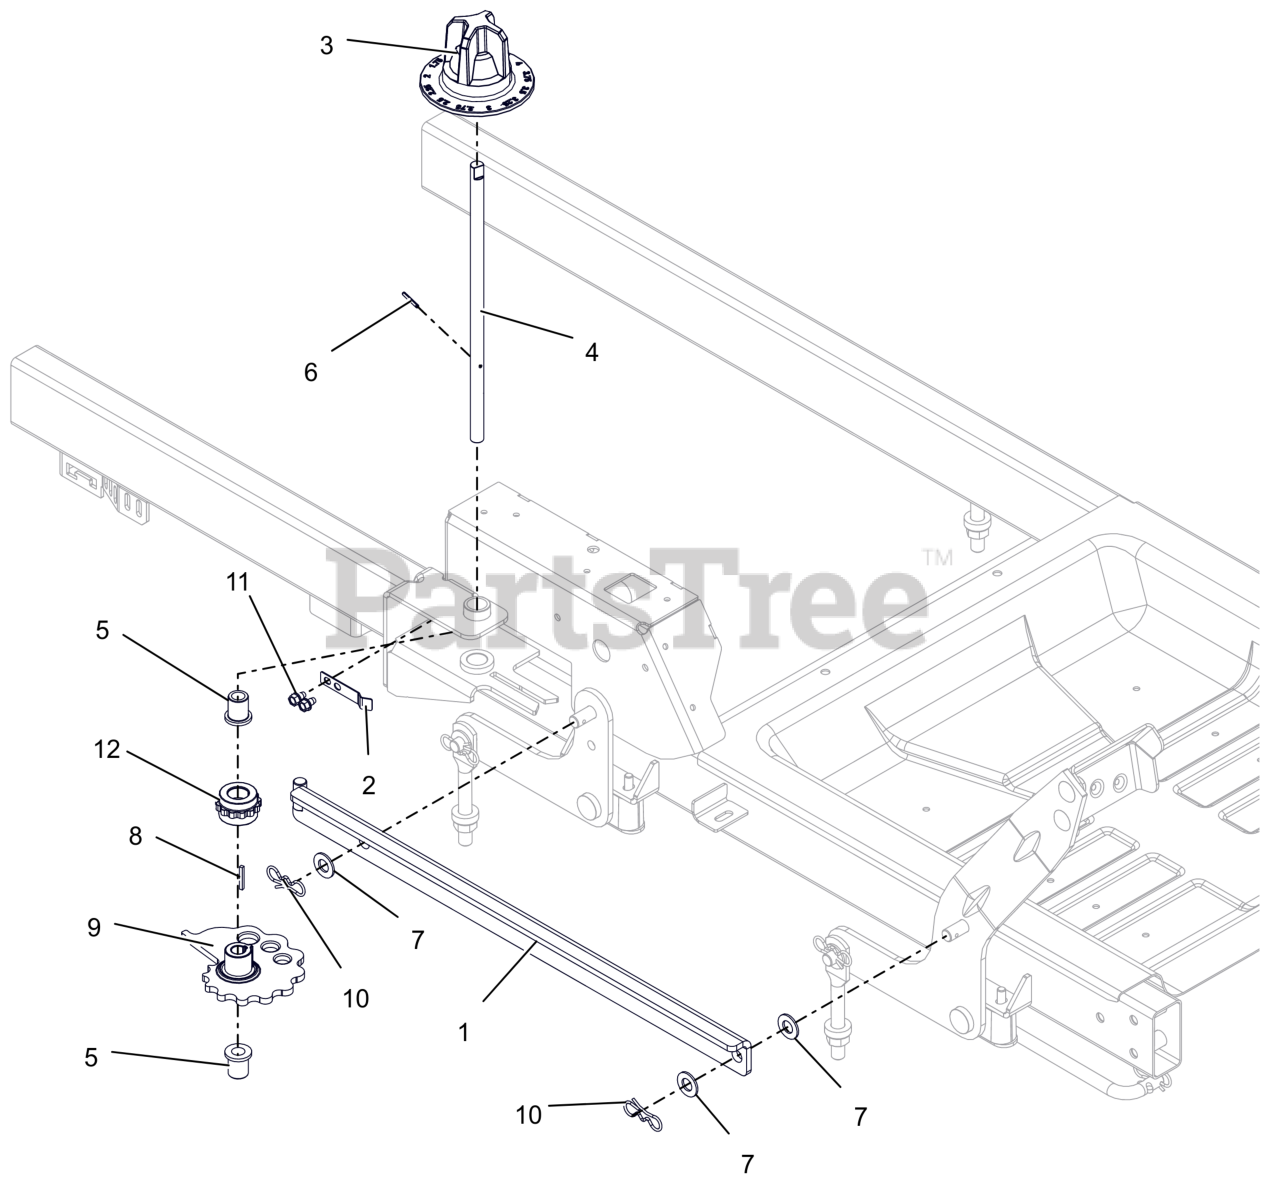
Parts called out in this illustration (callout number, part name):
1	WLDMT, HOC LINK
2	ARM, HOC DETENT
3	KNOB, HOC DIAL
4	SHAFT, HOC CAM IKON
5	BSHG-FLG, .503X.750X.875X1.00
6	PIN-ROLL .125X1.00
7	WSHR-FL-NYL .518X1.000X.080
8	KEY, 1/8 X 1/8 X 1.0
9	CAM, HOC (PM)
10	PIN, BOWTIE .091X1.875 ZCC
11	SCR,TAP .25-20X.375 HWH TR ZCC
12	GEAR, HOC INDEX
